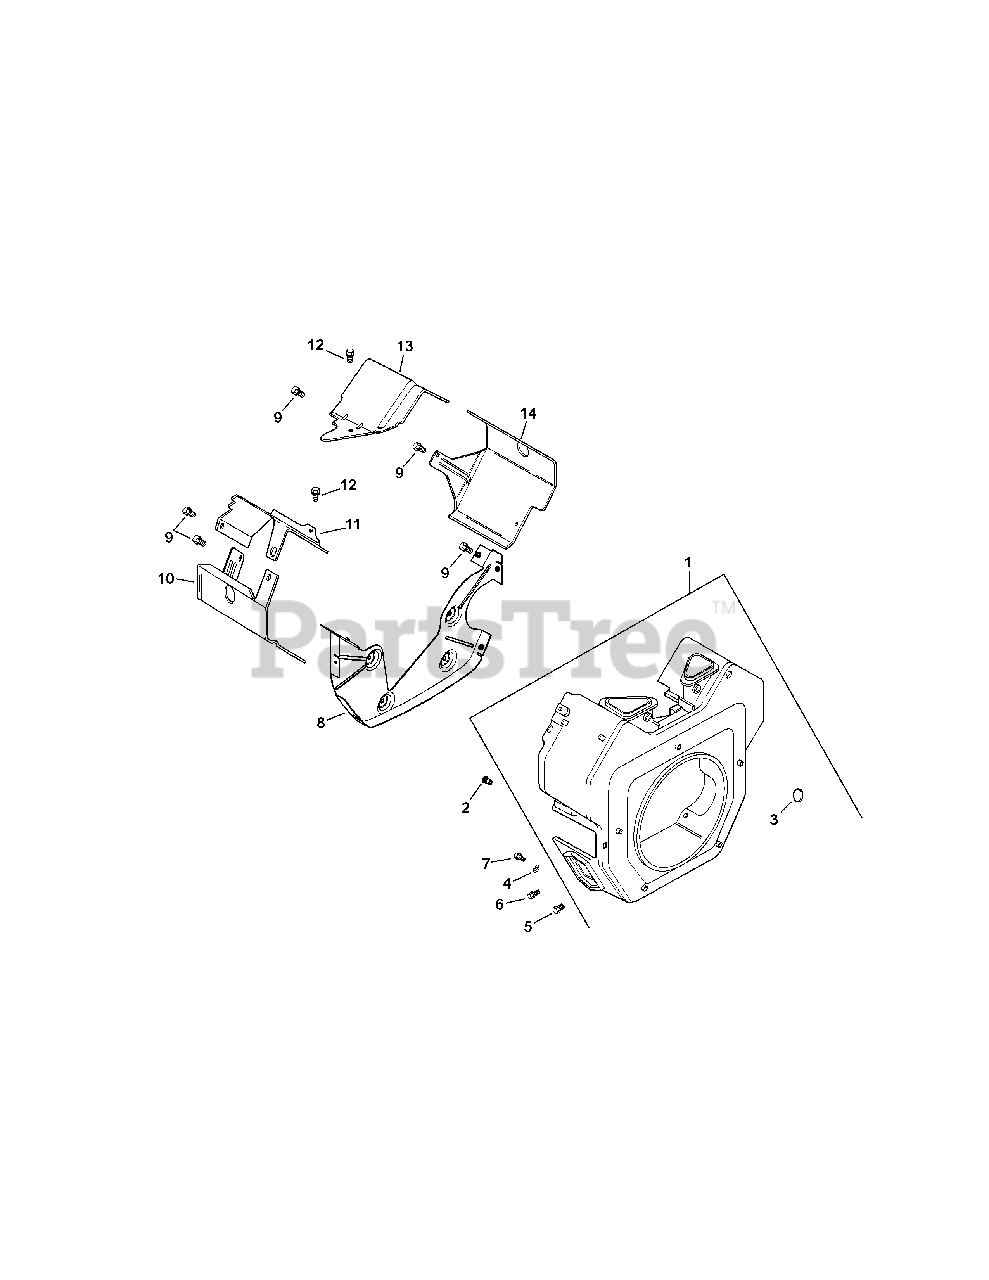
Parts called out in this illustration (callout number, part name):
1	Housing, blower
2	Insert, threaded (5)
4	Washer, flat, 7/32" (2)
5	Screw, hex. Flange M5x0.8x16
6	Screw, hex. Flange M5x0.8x16 (3)
7	Screw, hex. Flange M5x0.8x20 (4)
8	Plate, back (Incl KH-25-154-11-S)
9	Screw, hex flng (6) M6x1.0x16 (6)
10	Baffle, cyl barrel #2 side
11	Baffle, valley - #2 side
12	Screw, hex flange M5x0.8x10 (2)
13	Baffle, valley - #1 side
14	Baffle, cylinder barrel - #1 side
